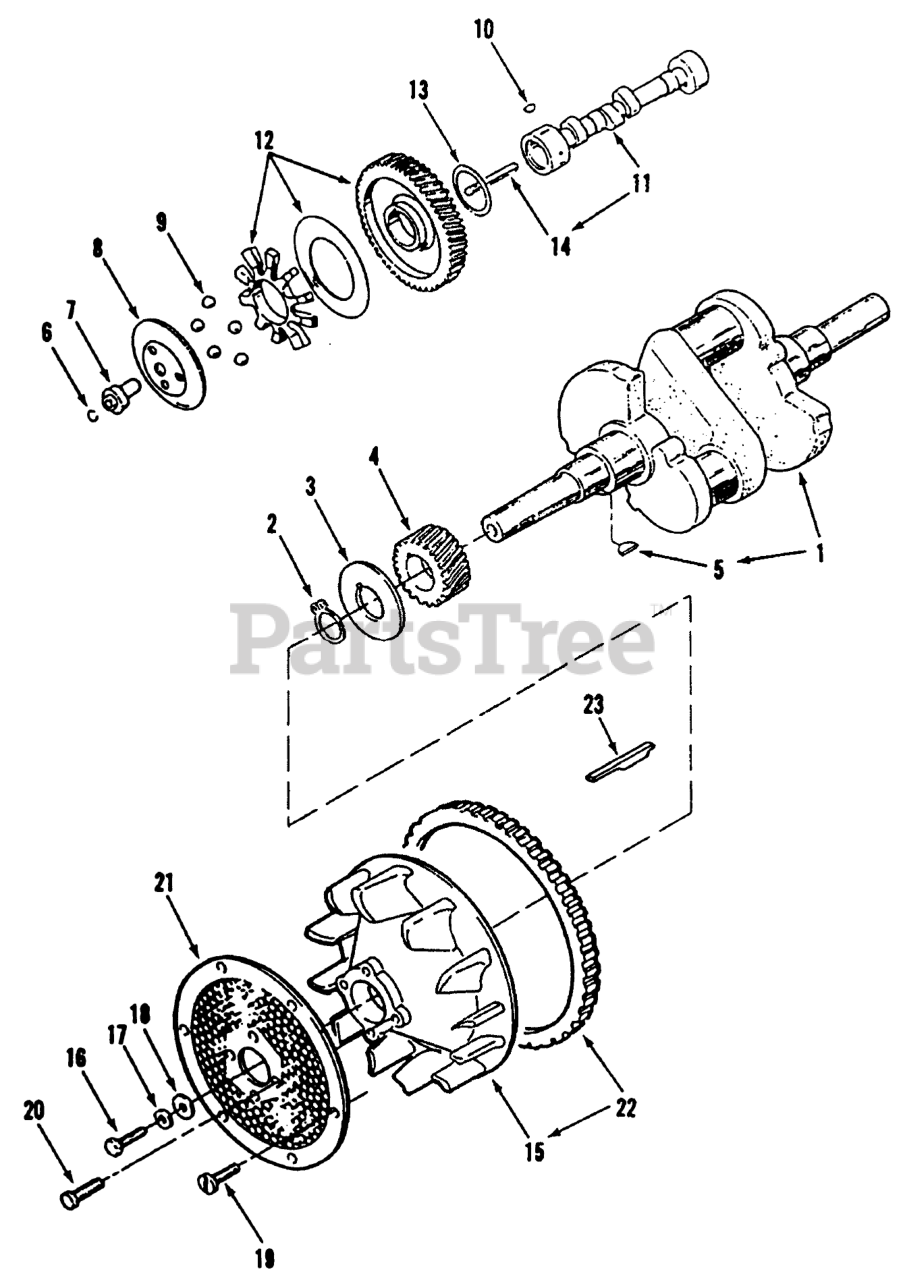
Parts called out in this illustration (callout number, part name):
1	CRANK-SHAFT
3	Washer
4	Gear
5	Key
6	Retaining Ring
7	Governor Cup Hub
8	Cup-Governor
9	BEARING
11	Camshaft (Includes Item 13)
12	Camshaft Gear (Includes Gear, Spacer, & Plate)
13	Washer
14	Pin
15	Flywheel (Includes Ring Gear)
16	Screw
17	WASHER-FLAT
18	Washer
19	Bolt
20	SCREW - CAP HEX HEAD
21	Screen
23	KEY - MACHINE
